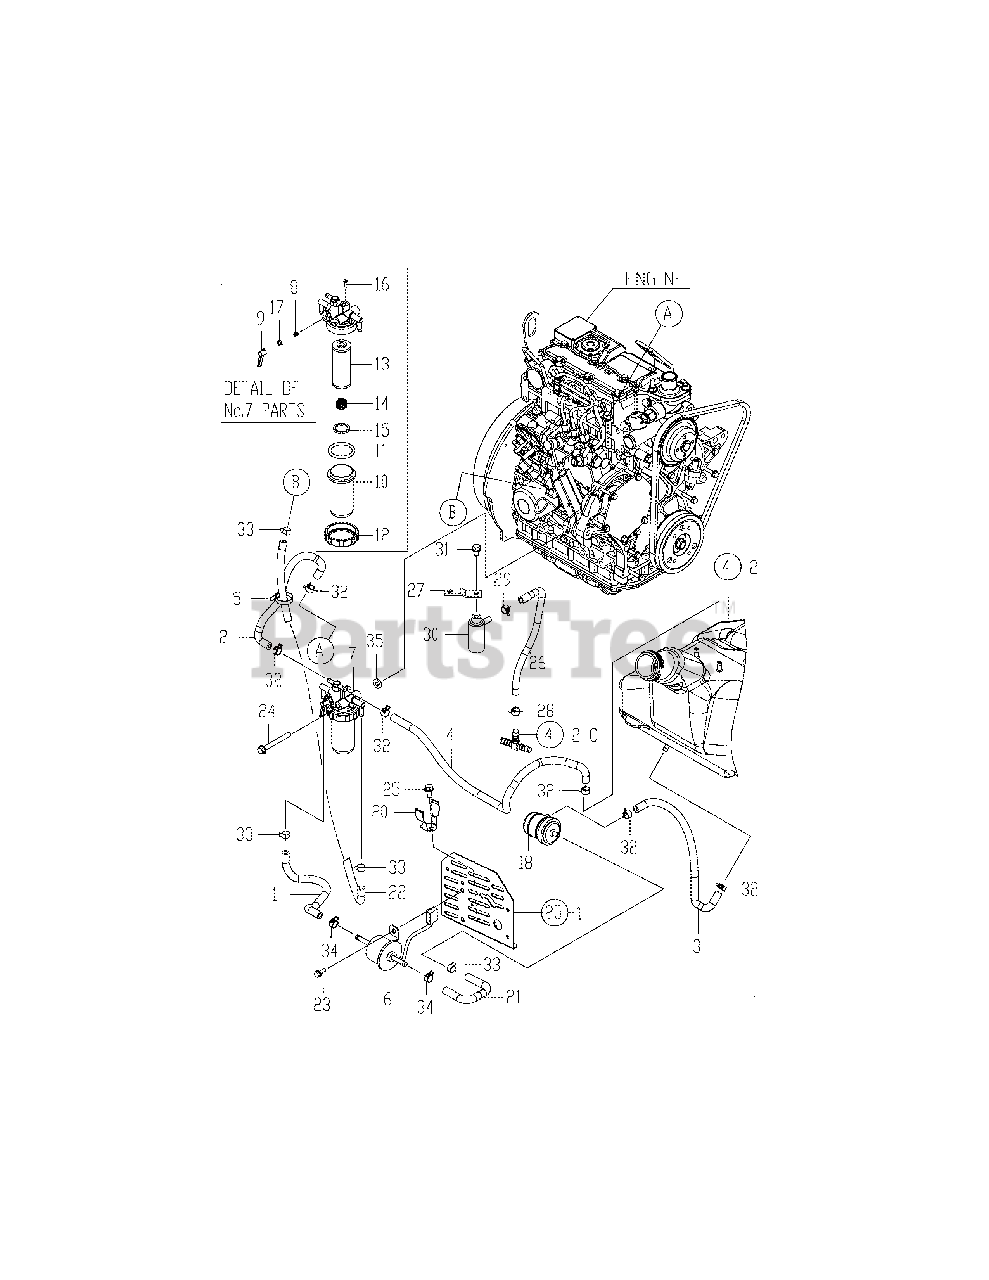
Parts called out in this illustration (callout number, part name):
6	Pump, Fuel Feed
7	Filter Assy, Fuel
8	Spring, Taper Valve
12	Ring, Retaining
13	Element, Filter
14	Spring, Screen
16	Screw, Handle M4
17	Packing, P 10A
18	Filter, Fuel Oil
21	Hose, 7.3 X 150
22	Hose, 7.3 X 330
24-1	Bolt M 8X 60 Plated
26	Hose, Air Vent
27	Support, Breather
